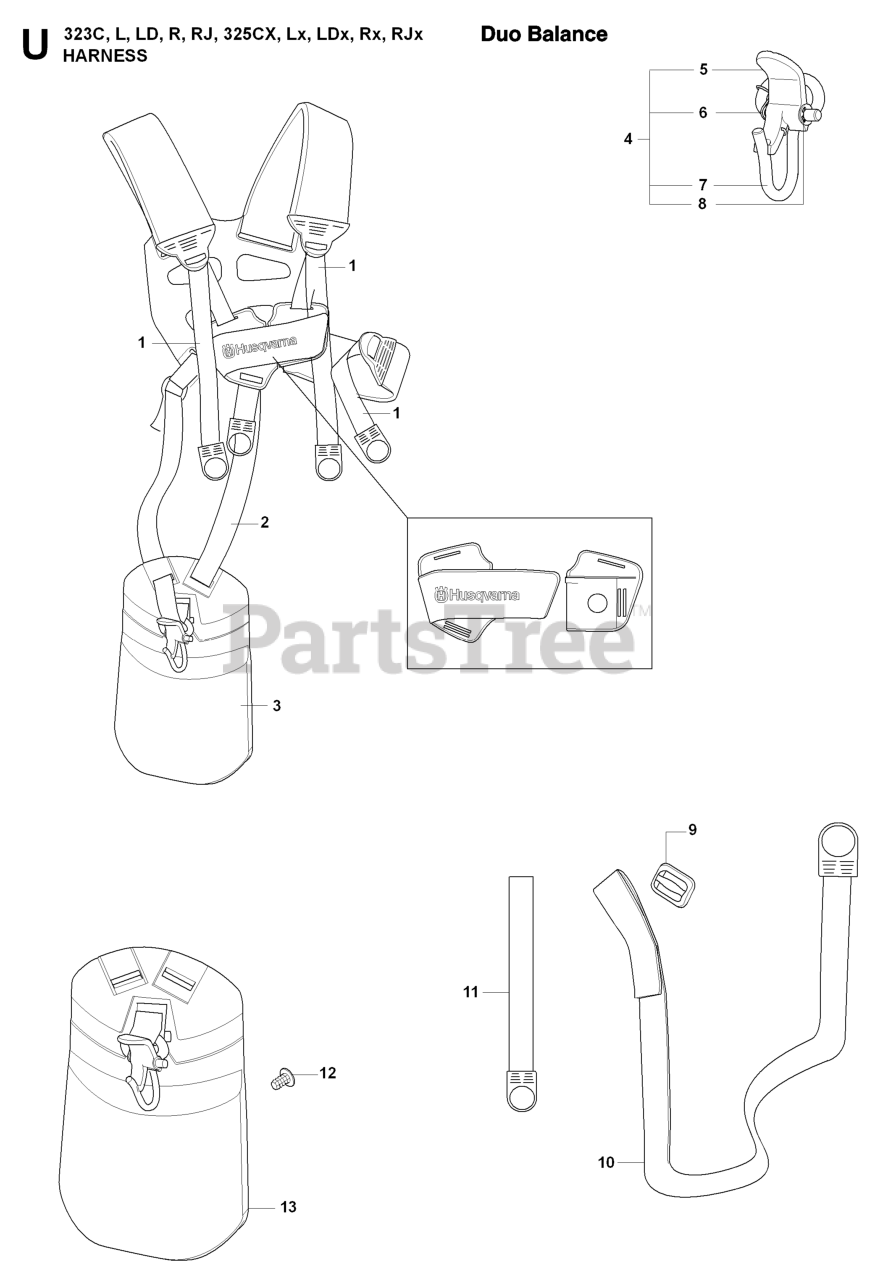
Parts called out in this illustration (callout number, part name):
4	HARNESS HOOK, COMPLETE
5	CATCH *
6	SPRING
7	HOOK
9	RP CLIP
